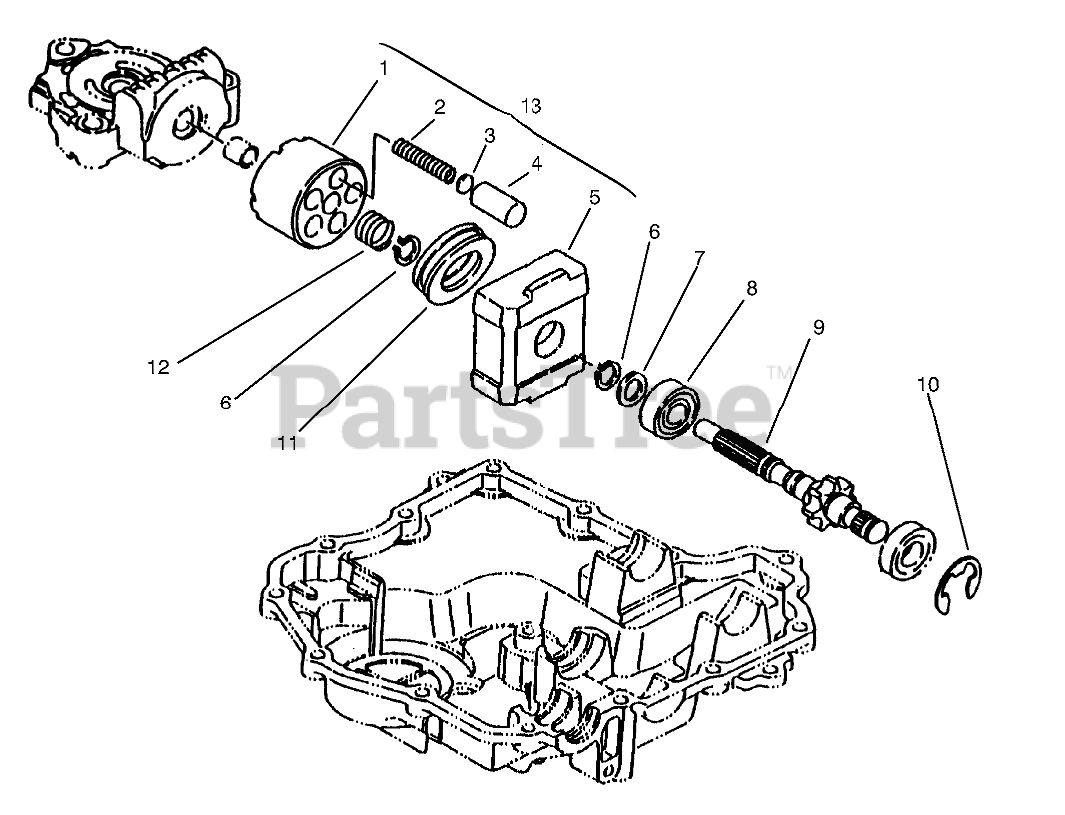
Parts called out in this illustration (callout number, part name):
1	Block-Cylinder
3	Washer
5	HOUSING
6	RING-SNAP
7	WASHER
8	BEARING-BALL
9	SHAFT - MOTOR
10	E-RING
11	BEARING-THRUST
13	ASM - CYCLINDER INC 6-9
